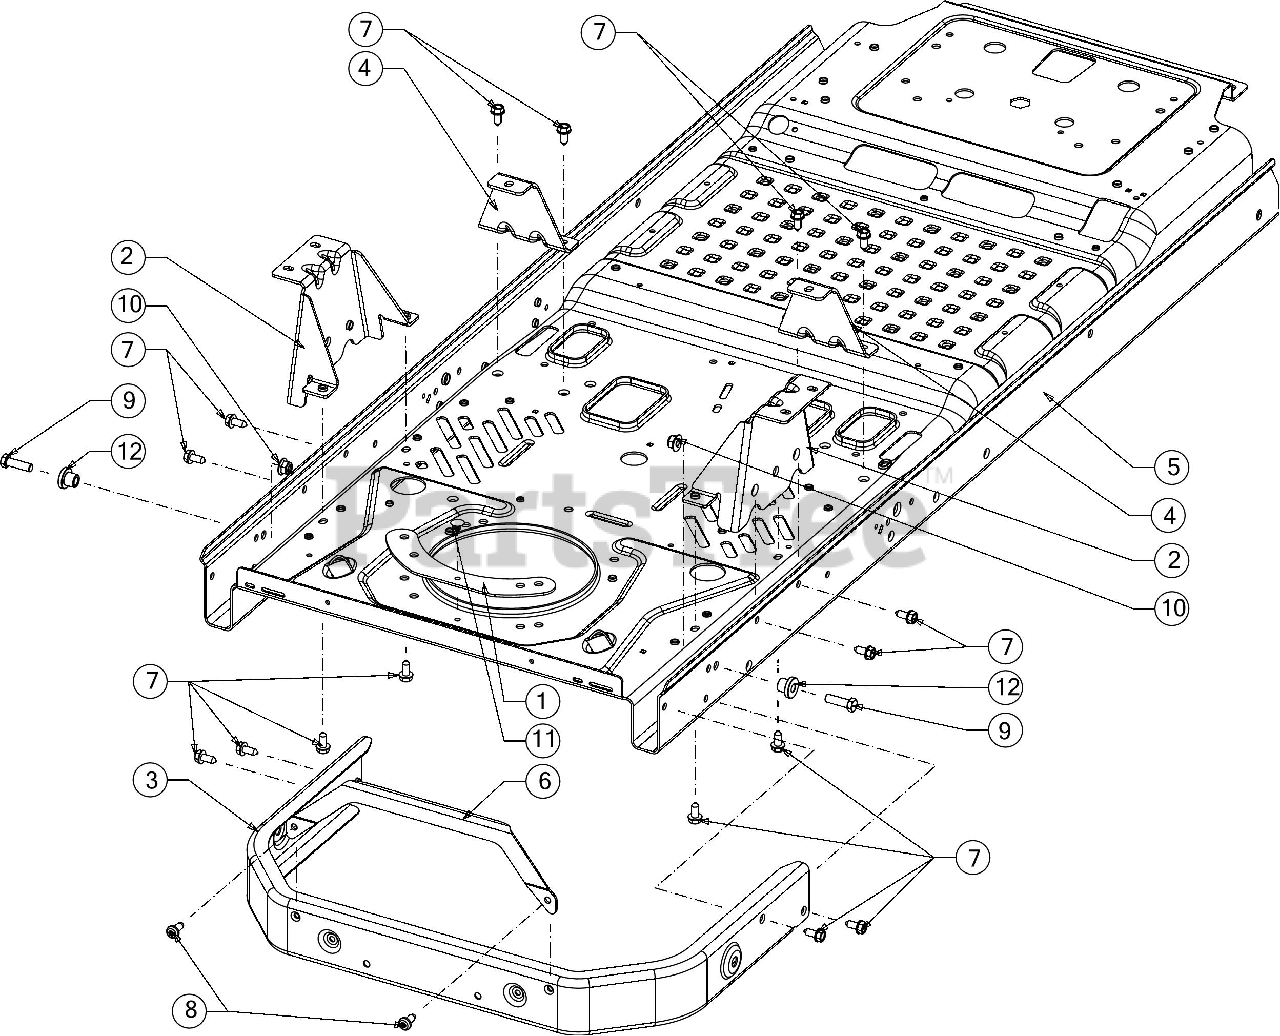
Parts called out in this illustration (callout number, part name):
1	RETAINER PLATE
2	TRANSMISSION MOUNTING BRACKET
4	TRANSMISSION MOUNTING BRACKET
6	MUFFLER SHIELDREAR
7	SCREW 5/16-18 X .750
8	SCREW 5/16-18 X.75
9	SCREW 3/8-16 X 1.25 GR5
11	RATCHET CLIP
12	SHOULDER SPACER
